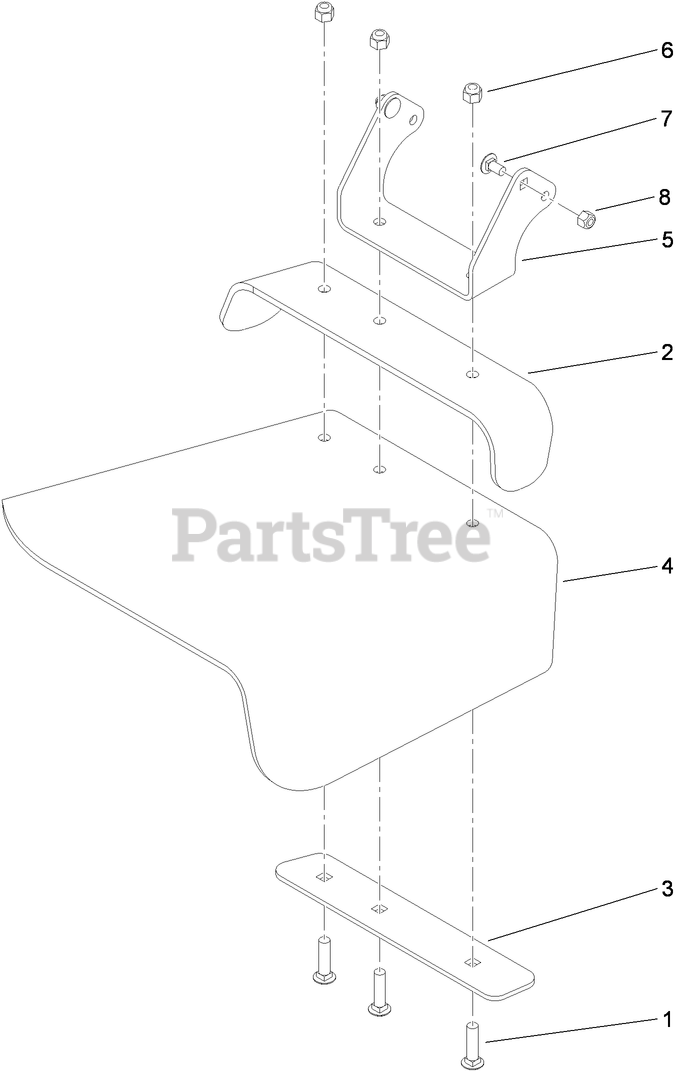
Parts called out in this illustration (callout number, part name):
1	SCREW-CARR
2	STRAP-DEFLECTOR, TOP
3	STRAP-DISCHARGE
4	DEFLECTOR-RUBBER
5	BRACKET-MOUNTING, DEFLECTOR
6	NUT-LOCK, NI
7	SCREW-CARR
8	NUT-LOCK, NI
